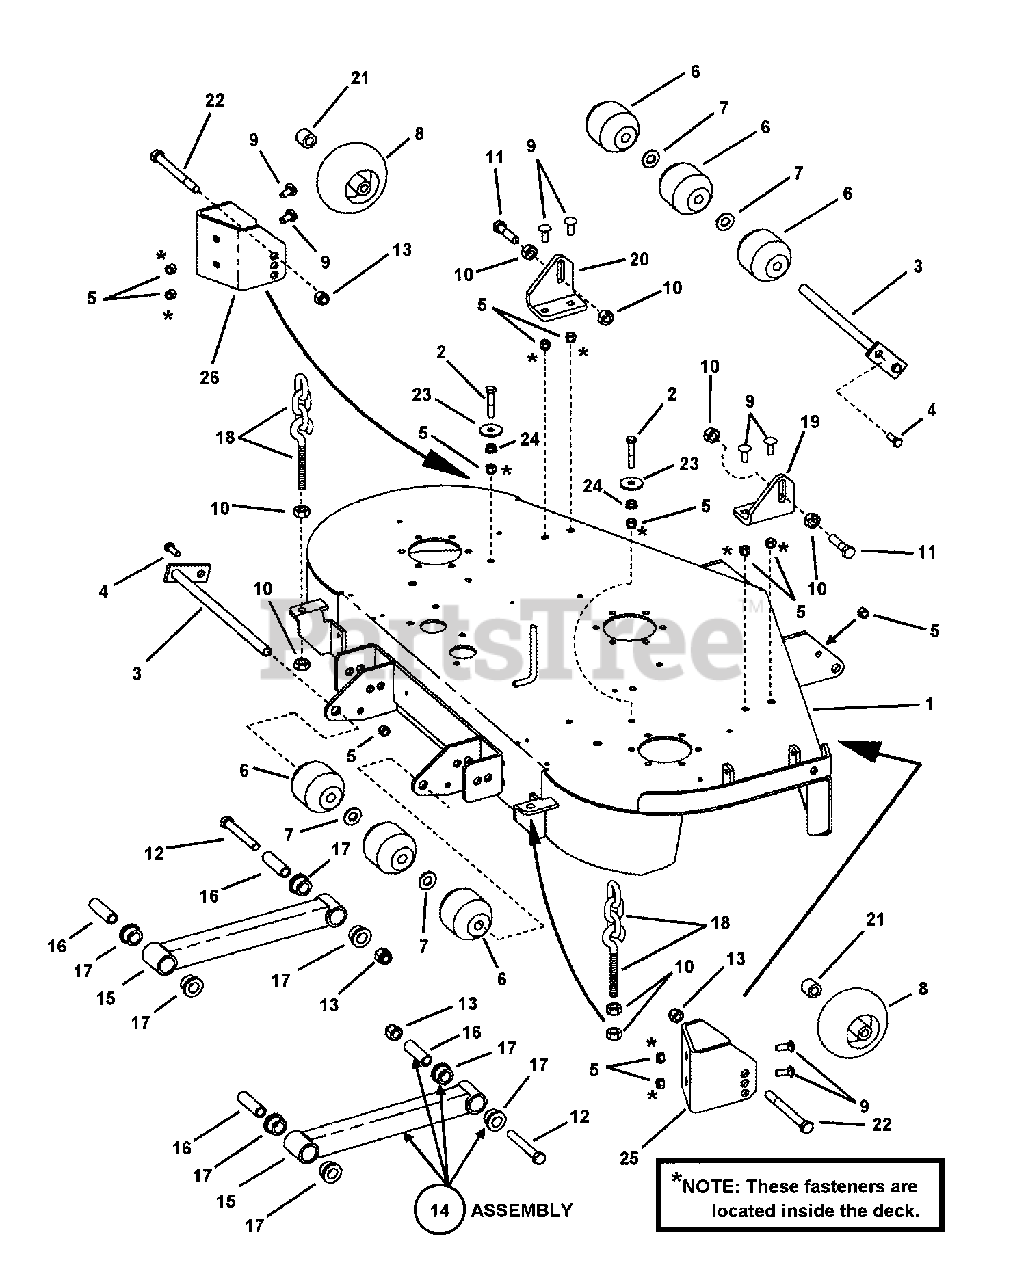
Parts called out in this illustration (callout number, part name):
1	WELDMENT, 48" Deck
2	BOLT, 3/8-16 X 2, GD5, CZ
3	WELDMENT Pivot Pin
4	BOLT, 3/8-16 X 1" GD5 CZ
5	NUT, 3/8-16 HEX NYLON LOCK
6	ROLLER Low Density Polyethylene
7	WASHER, 5/8" Flat SAE
8	GAUGE WHEEL, Polyethylene
9	BOLT, 3/8-16 x 1" Square Neck Carriage GR 5
10	NUT, 1/2-13 HEX
11	SCREW, 1/2-13 x 2" Hex Head Cap, GR5
12	BOLT, 1/2-13 x 3-3/4" Hex Head Cap, GR5
13	NUT, 1/2-13 HEX NYLON LOCK
15	WELDMENT, Pusher Bar
16	SLEEVE - Suspension
17	BUSHING - Suspension
18	ASSEMBLY, Chain & Eyebolt (see Front Frame Assy page)
19	BRACKET, Front Deck Lift, Right Hand (Series 0)
20	BRACKET, Front Deck Lift, Left Hand (Series 0)
21	SPACER, Gauge Wheel
22	BOLT, 1/2-13 X 5 GD5 YZ
23	WASHER, .406 x 1.50 x .120 Flat
24	NUT, 3/8-16 HEX SERRATED FLANGE
25	WHEEL BRACKET Front Right
26	WHEEL BRACKET Front Left
